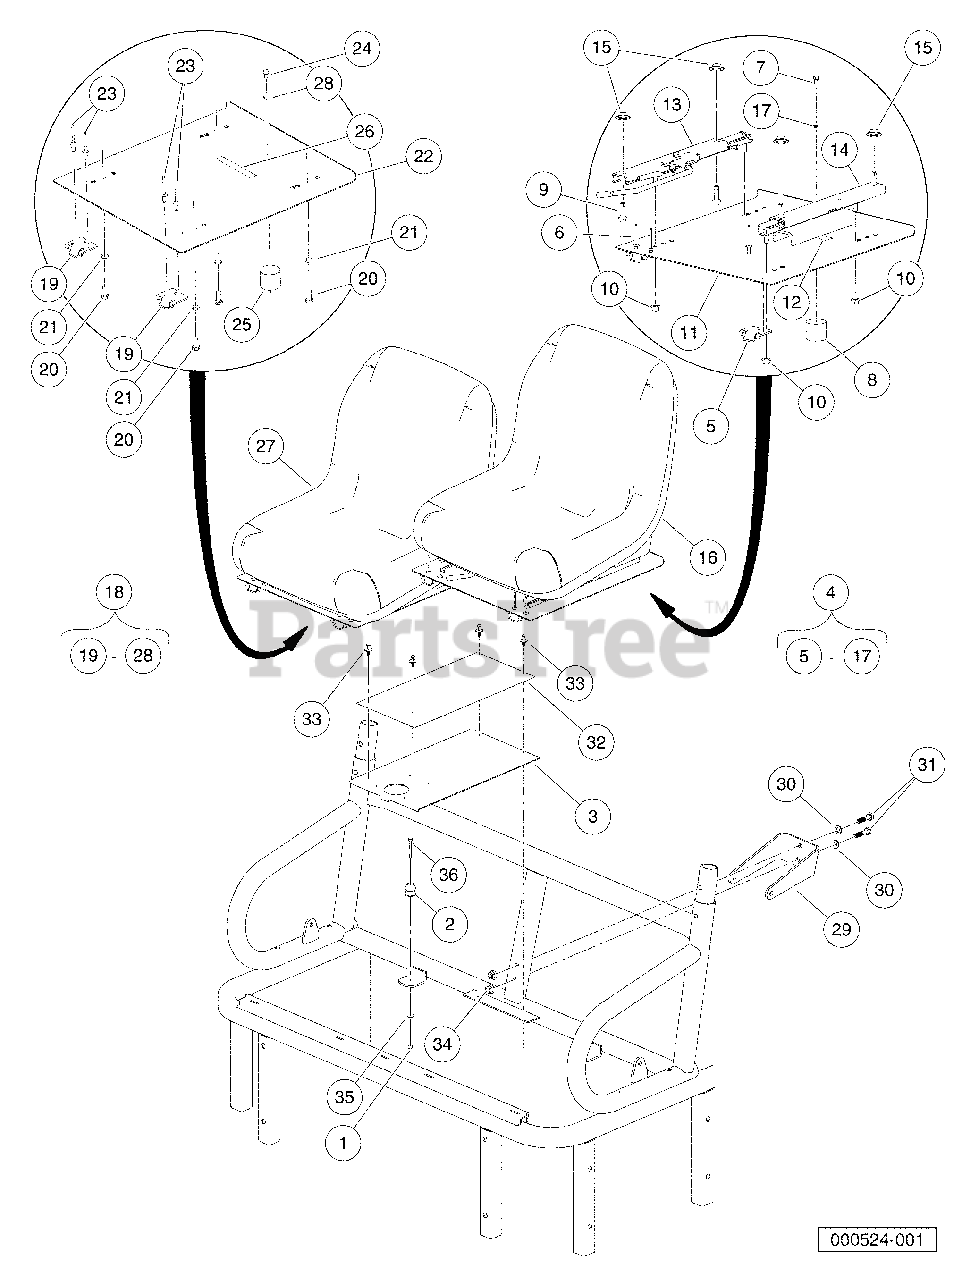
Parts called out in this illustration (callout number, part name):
1	Locknut, M6-1.00 Nylon Insert
2	Seat Holder Base
3	Pan, Center, Closeout
4	Asm, Bucket Seat Adjustable
5	Hinge Plate.
6	Rivet, 1/4 X .438 Blind
7	Screw, 6m-1.00 X 10mm Hex Head
8	Seat Holder Cup
9	Bolt, Flange Head, M8 X 30.0
10	Nut,m8,all Metal Lock
11	Pan, Seat, Driver Asm
12	Decal, Hot Surface Warning
13	Adjuster, Forward/Aft
14	Adjuster, Slider
15	Washer, Bell
16	Seat, Bucket, Gray
17	Lockwasher, 1/4 Helical Split
18	Assembly, Bucket Seat w/Spacers
19	Hinge Plate.
20	Screw, M8-125 X 22 Hex-Head
21	Lockwasher, 8mm Split
22	Pan, Seat, Passenger
23	Rivet, 1/4 X .438 Blind
24	Screw, 6m-1.00 X 10mm Hex Head
25	Seat Holder Cup
26	Decal, Hot Surface Warning
27	Seat, Bucket, Gray
28	Lockwasher, 1/4 Helical Split
29	Bracket, Seatbelt, Bolt-On
30	Washer, Hard, M10, Zn-Ni/Blk
31	Bolt, M10 X 45, Zn-Ni
32	Cover, Center Console
33	Rivet, Removable, Tuflok 1/4"
34	Nut, Flanged, M10 x 1.5, Black
35	Washer, 1/4 Type A Narrow Flat
36	Bolt, M6 X 1 X 45
